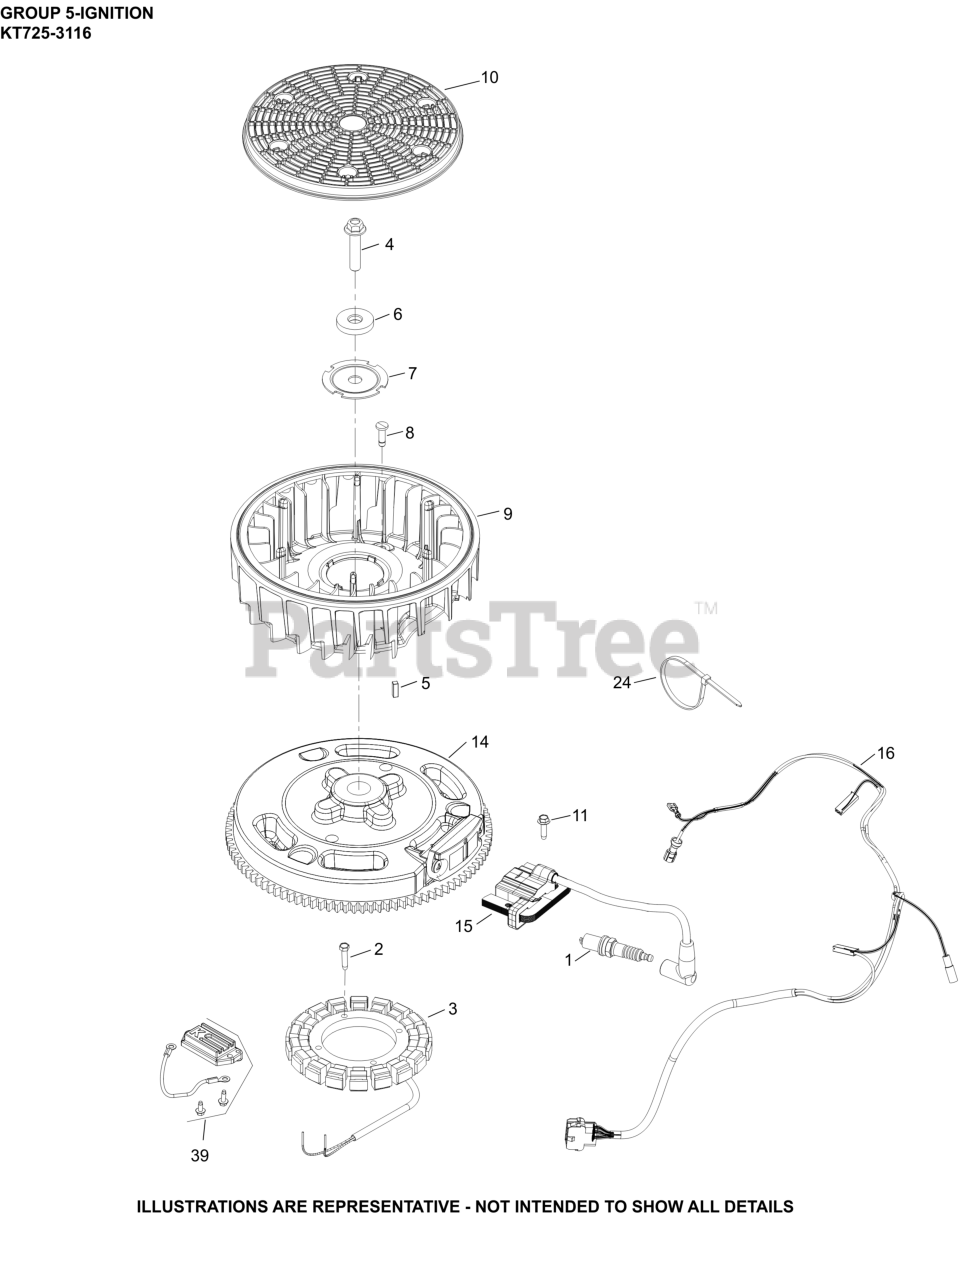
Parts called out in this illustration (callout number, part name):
1	SPARK PLUG, RFI
2	SCREW, THREAD FORMING
3	KIT, 15 / 20 AMP STATOR
4	SCREW, HEX FLANGE
5	KEY, SQUARE
6	WASHER, FLAT
7	PLATE, FAN MOUNTING
8	RETAINER, FLYWHEEL FAN
10	SCREEN, GRASS
11	SCREW, THD FRM-USE 25 086 473-S
14	FLYWHEEL ASSEMBLY
15	MODULE, CDI IGNITION
16	HARNESS, WIRING ASSEMBLY
39	KIT, REGULATOR RECTIFIER
